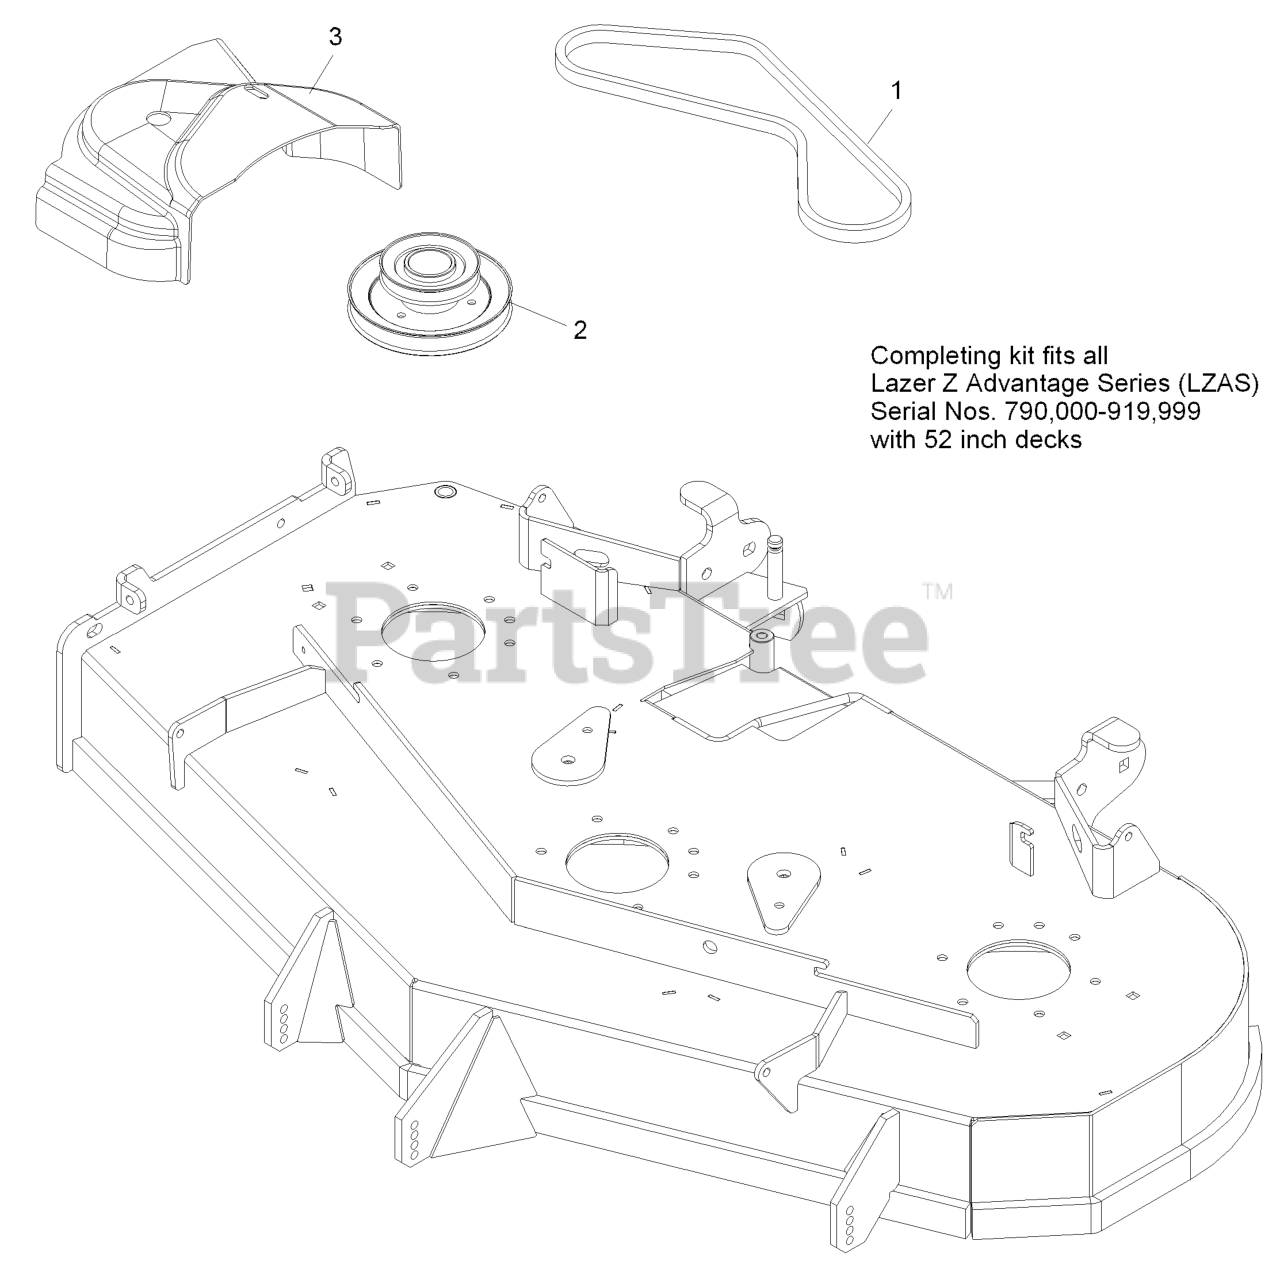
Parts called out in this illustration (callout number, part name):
1	BELT, BLOWER 52"DECK
2	JACKSHAFT,UV DRIVE 524
3	COVER,BELT UV 52
